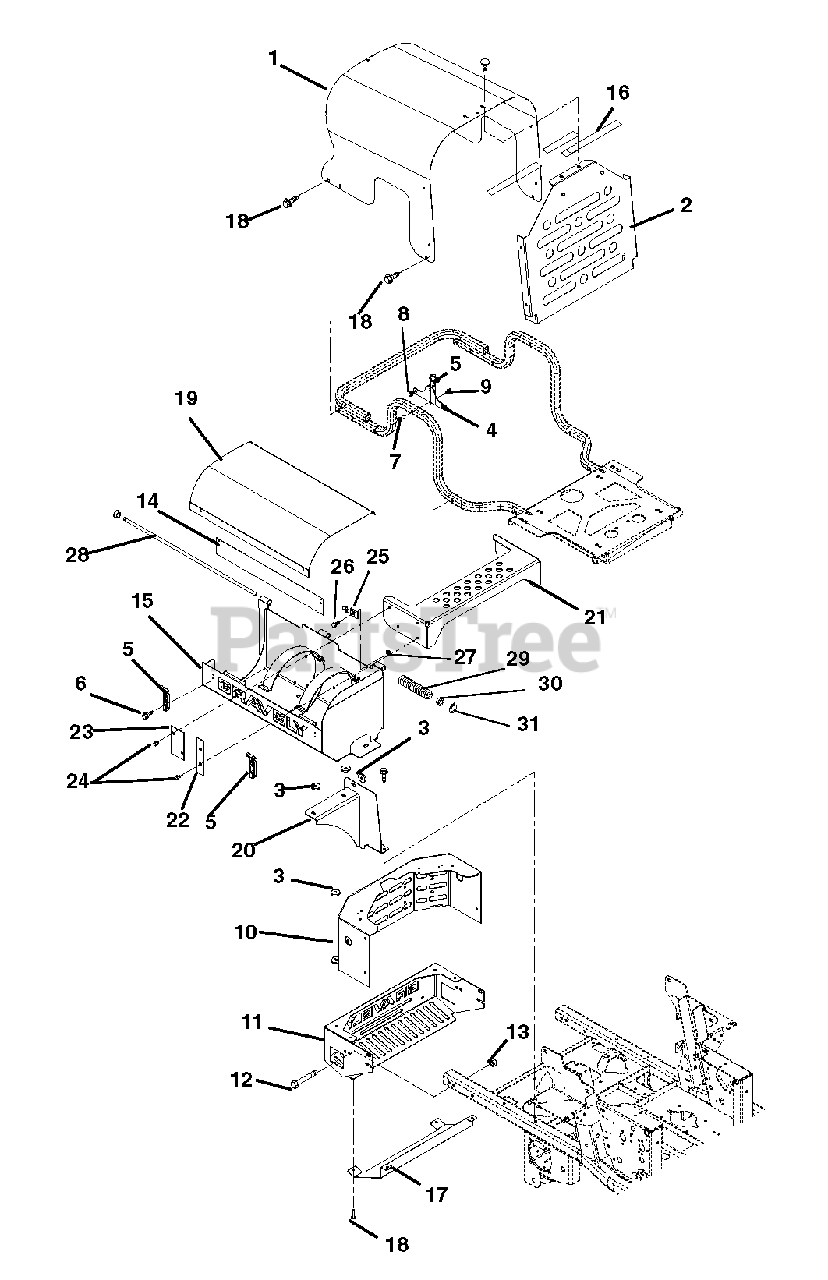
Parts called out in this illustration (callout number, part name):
1	Hood, 200 XDZ LPG
2	Shroud, Hood
3	Washer, Flat Steel .406 x 1.50 x .245
4	Bracket, Latch Stop
5	Latch, Rubber
6	Screw, Machine 10-24 x .50 Hex Washer Head
7	Screw, Machine 10-24 x 1.50 Hex Washer Head
8	Button Bumper
9	Nut-Spin Lock-Flange .312-18
10	Guard, Rear Engine 200 XDZ LPG
11	Bumper, Rear
12	Bolt, Hex .38-16 x 2.75 Grade 5
13	Nut-Locking-Top-Flange .38-16
14	Plate, Name Backer LPG
15	Weldment, Tank Housing RH
16	VHB Tape 4941F
17	Heat Shield
18	Screw-Tapping .38-16 x .50 Hex Washer Head Thread Rolling YWZ
19	Weldment, Cover Tank RH LPG
20	Weldment, RH Tank Support
21	Weldment, Tank Support
22	Plate, LPG Tank Support Backer
23	Plate, LPG Tank Support Backer
24	Bolt, Round Head Square neck .38-16 x 1.25
25	Thumb Latch
26	Screw, Machine 10-24 x .50 Hex Washer Head
27	Nut, Locking-Nylon 10-24 with Insert
28	Rod, Tank Cover Hinge LPG
29	Spring, Compression .06 ID x 9.5
30	Bushing-Flange
31	Ring, Retaining-External .500 x .050
